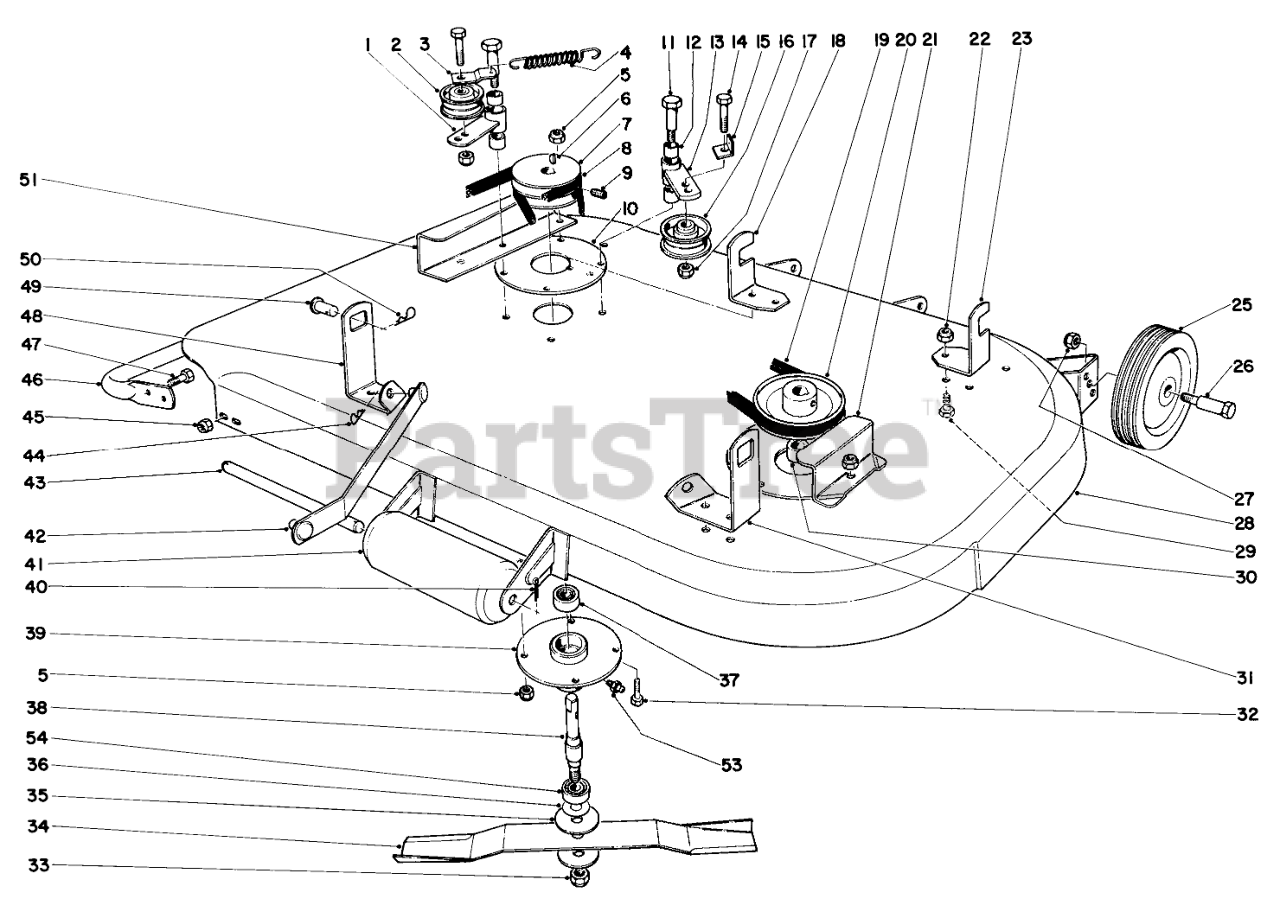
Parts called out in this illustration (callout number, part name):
1	Idler Plate Incl. Ref. #11
2	Flat Idler
4	Spring Tension
5	Nut
6	KEY-WOODRUFF
7	BLD SPDLE PULLEY (MACH)
8	Belt
9	SCREW-SET, HSH
10	Washer
11	SHOULDER BOLT
12	Bushing
13	Idler Plate
14	SCREW-HH
16	Pulley
18	Bracket
20	Pulley
21	Belt Guard
22	Nut
23	Bracket Mower
25	Wheel
28	Housing
29	SCREW-HH
30	Spacer
31	Bracket-Mower
32	SCREW-HH
34	Blade
35	WASHER
36	WASHER
37	Bearing
38	BLADE SPINDLE
39	Mower Spindle Housing
40	PIN-COTTER
41	Roller
42	Tow Bar
43	ROLLER SHAFT
44	PIN-COTTER
46	Mower Guard
47	SCREW-CARR
48	Bracket-Mower
50	PIN-COTTER
51	Guard Mower
53	FITTING-GREASE
54	.6693 RP BALL BEARING
